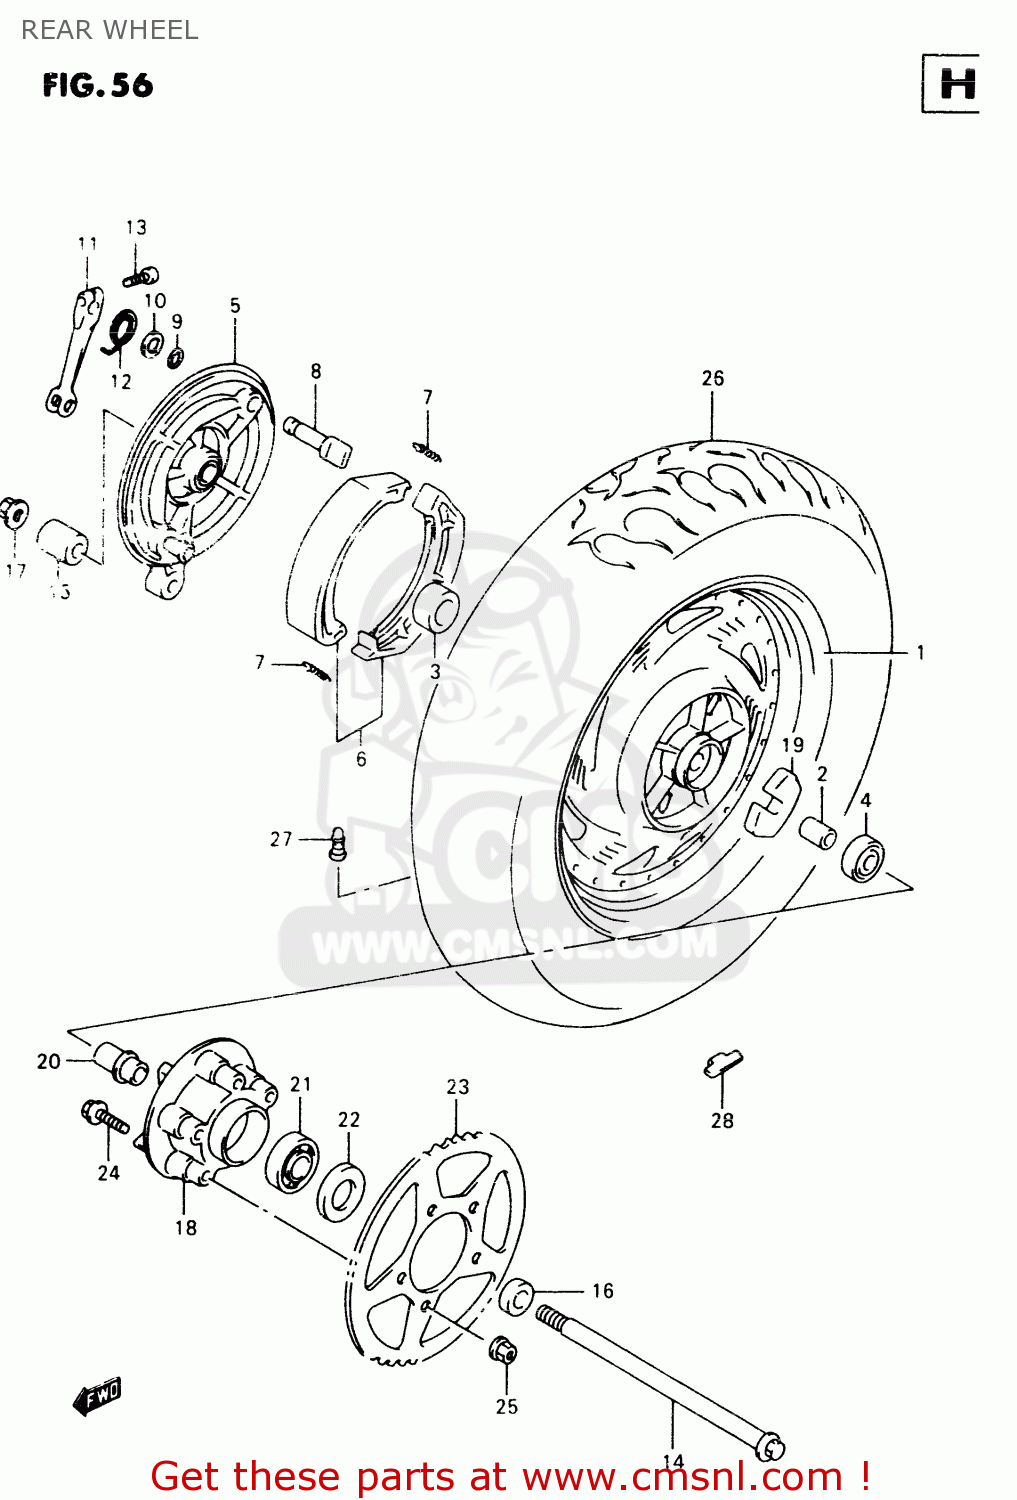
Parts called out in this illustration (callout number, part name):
1	WHEEL,RR(15M/CXMT3.50)
2	SPACER(17.5X25X70)
3	BEARING
4	BEARING
5	PANEL,RR BRAKE ANCHOR
6	SHOE SET,BRAKE (NAS)
7	SPRING,BRAKE SHOE
8	CAM,RR BRAKE
9	O RING(D:2.4,ID:14.8)
10	WASHER(15.5X24X1.6)
11	LEVER,RR BRAKE CAM
12	SPRING
13	BOLT
14	AXLE,RR
15	SPACER(17X33X35.3)
16	SPACER,RR AXLE,L
17	NUT
18	DRUM,RR SPROCKET MOUNTING
19	ABSORBER,RR HUB SHOCK
20	RETAINER,RR SPROCKET DRUM
21	BEARING(25X62X17)
22	SEAL,OIL(35X62X8)
23	SPROCKET,RR(NT:48-530)
24	BOLT
25	NUT
26	TIRE,RR(150/90 15M/C 74H)
27	VALVE ASSEMBLY,WHEEL,TR412
28	WEIGHT,BAL. 30
